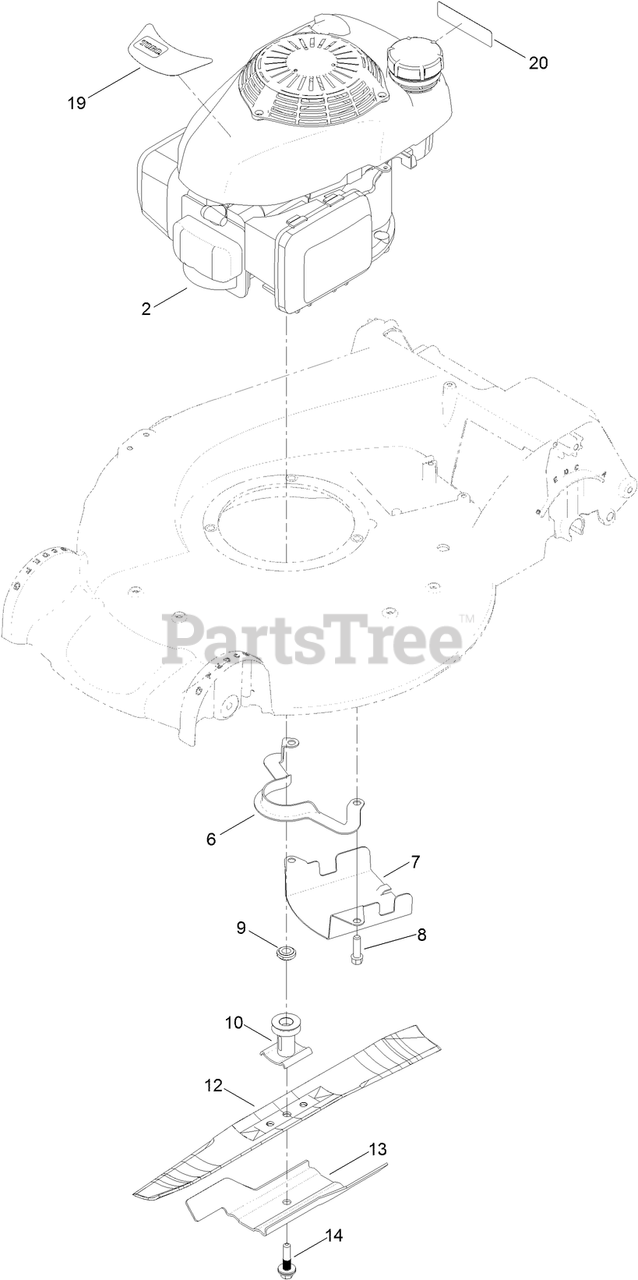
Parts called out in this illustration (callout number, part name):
6	GUIDE-BELT
7	SHIELD-GRASS
8	SCREW-TAPTITE
9	Spacer-Driver
10	DRIVER-BLADE
12	BLADE-RECYCLING
13	Accelerator-Blade
14	BOLT-BLADE
19	DECAL-SHROUD, HONDA
20	DECAL-ARRESTER, SPARK
